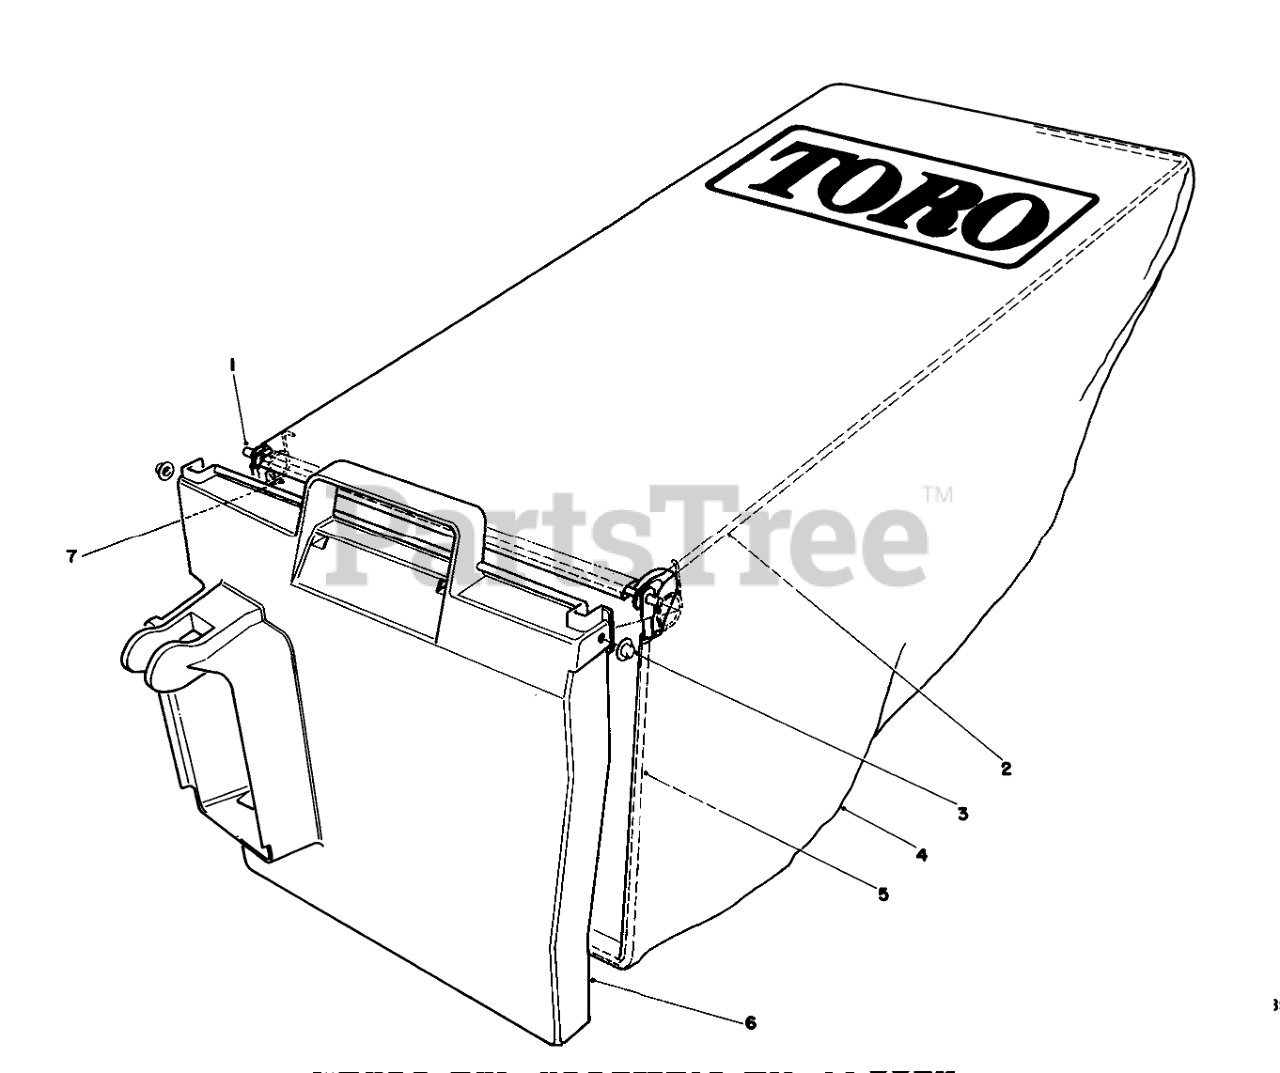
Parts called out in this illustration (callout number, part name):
1	HINGE PIN
2	BAG FRAME
3	NUT-PUSH
5	BAG FRAME
6	GRASS BAG DOOR
7	SPRING
